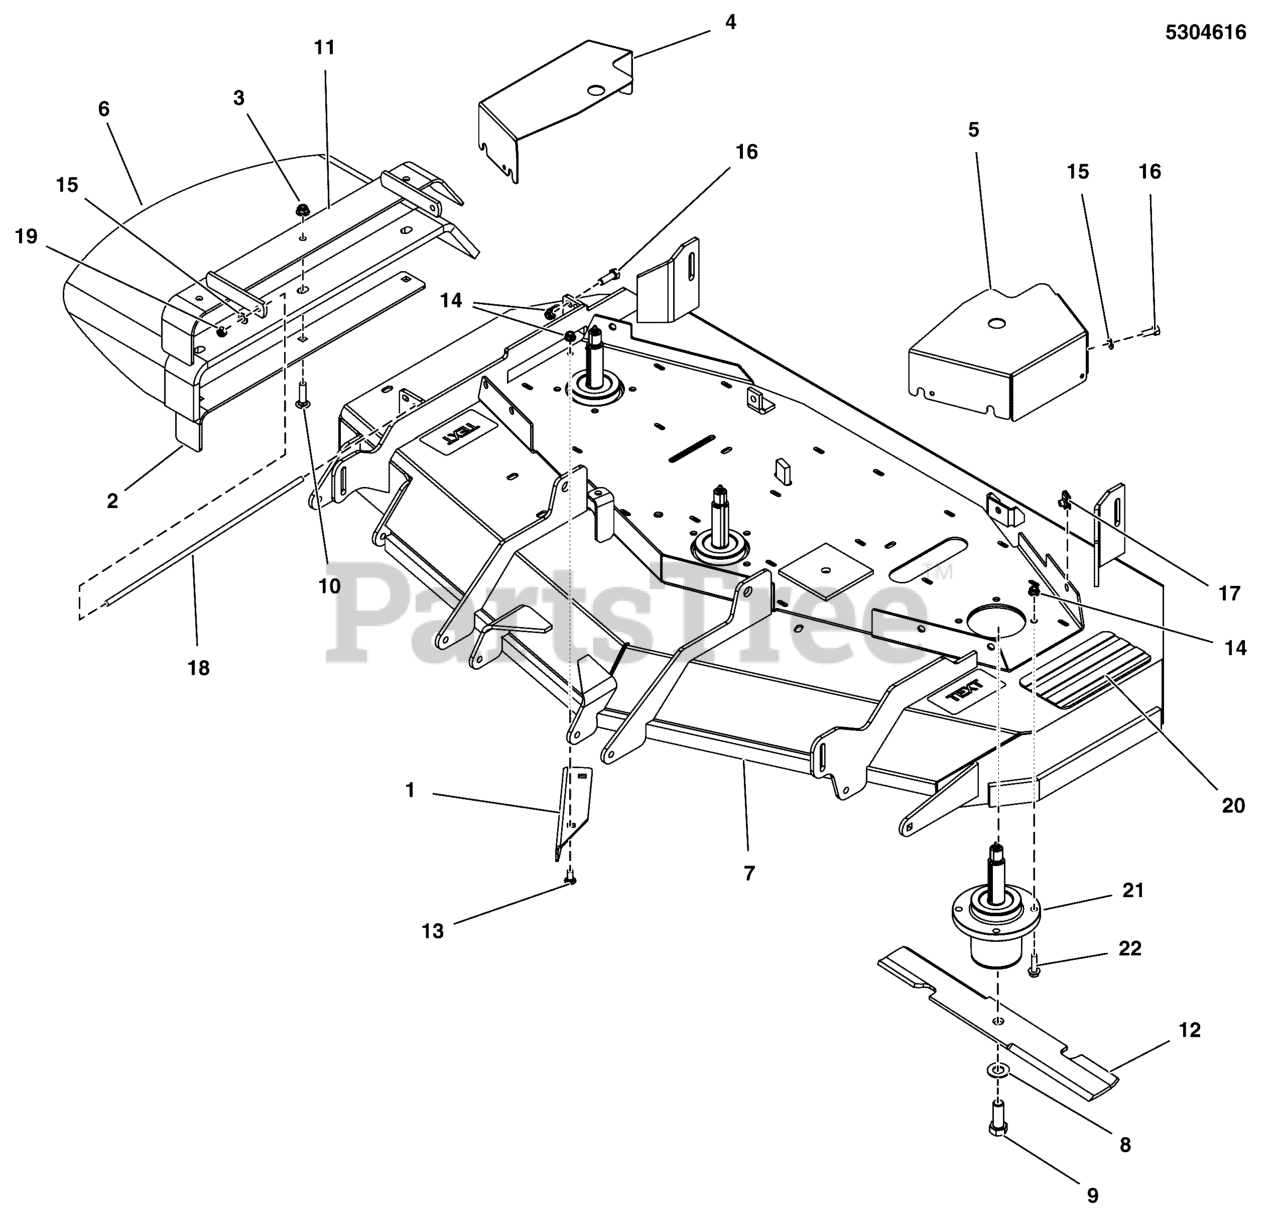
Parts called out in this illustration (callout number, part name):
1	PLATE, DEFLECTOR, 52 DECK - BLK
2	SUPPORT, DISCHARGE CHUTE - BLK
3	NUT, 3/8 - 16 HEX NYLOCK FLANGE
4	GUARD, 52 DECK, RH - RED
5	GUARD, 52 DECK, LH - RED
6	CHUTE, RUBBER DISCHARGE (5104442)
7	DECK SHELL W/DECALS, 52, 2100Z (5415324B)
7	DECK SHELL W/DECALS, 52, 2100ZSD,EXP (5415324B)
8	WASHER, BLADE BOLT, 9/16" F436, CZ
9	BOLT, 5/8-11 X 1-3/4 GD8
10	BOLT, 3/8-16 X 1-1/2, CARRIAGE, GD5, CZ
11	WELD, MOUNT, DISCHARGE CHUTE - BLK
12	BLADE, 18 X .25 X 2.5, 1 X 3.5 (SET OF THREE)
13	BOLT, 5/16-18 X 3/4, CARRIAGE, GD5, CZ
14	NUT, 5/16-18 HEX NYLOCK FLANGE NUT
15	WASHER, 5/16" SAE
16	BOLT, 5/16-18 X 3/4 GD5
17	BODY CLIP, 5/16-18-7GA MATERIAL
18	ROD, MOUNT, CHUTE, 61, CZ
19	NUT, 5/16-24 HEX NYLON LOCK
20	SAFETY WALK, 4.00 X 7.50
21	SPINDLE ASSM, ALUMINUM, LONG SHAFT
22	BOLT, Flange Head, 5/16-18 x 1-1/4
